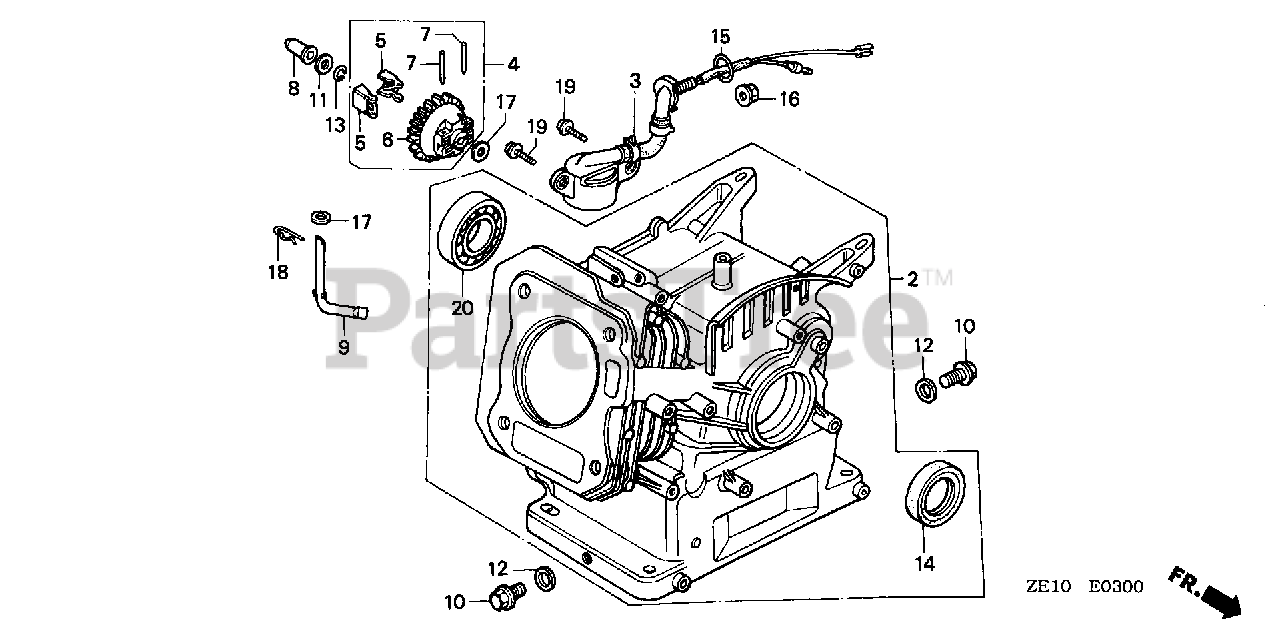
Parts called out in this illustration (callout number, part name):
2	CYLINDER ASSY. (OIL ALERT)
3	SWITCH ASSY., OIL LEVEL
4	GOVERNOR ASSY.
5	WEIGHT, GOVERNOR
6	HOLDER, GOVERNOR WEIGHT
7	PIN, GOVERNOR WEIGHT
8	SLIDER, GOVERNOR
9	SHAFT, GOVERNOR ARM
10	BOLT, DRAIN PLUG
11	WASHER, THRUST (6MM)
12	WASHER, DRAIN PLUG (10.2MM)
13	CLIP, GOVERNOR HOLDER
14	OIL SEAL (25X41X6)
15	O-RING (14MM) (ARAI)
15	O-RING (14MM) (NOK)
16	NUT, FLANGE (10MM)
17	WASHER, PLAIN (6MM)
18	PIN, LOCK (8MM)
19	BOLT, FLANGE (6X12)
20	BEARING, RADIAL BALL (6205TMB) (NTN)
20	BEARING, RADIAL BALL (6205)
